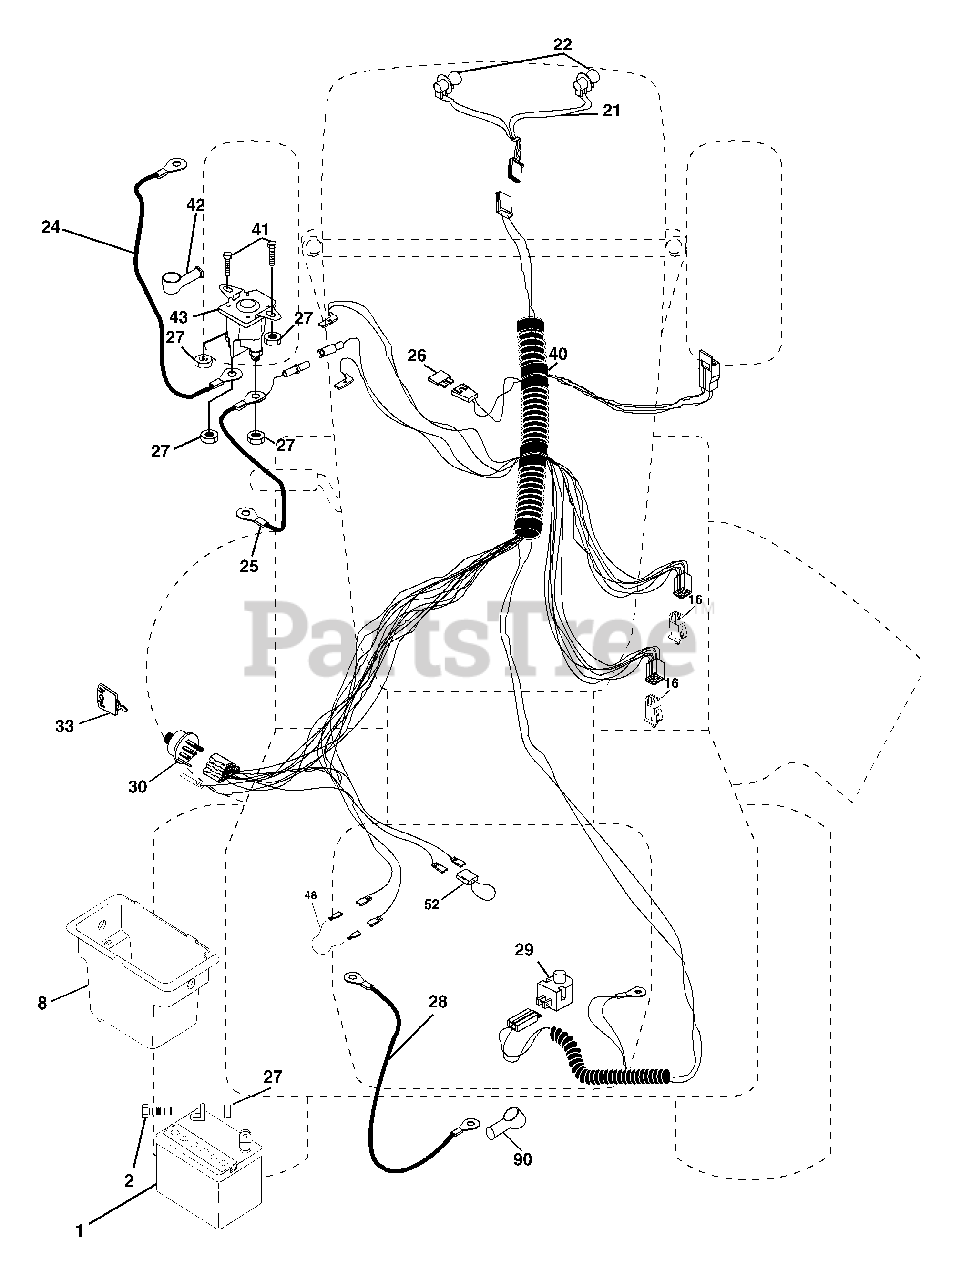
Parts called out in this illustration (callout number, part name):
1	Battery
2	Bolt, Hex Head 1/4-20 unc x 3/4
8	Box Battery Fender
16	Switch, Interlock
21	Harness, Light Socket
22	Bulb, Light
24	Cable, Battery, 6 Ga. Red, 11"
25	Cable, Battery, 6 Ga. Red, W/16 Wire
26	Fuse
27	Nut Keps Hex 1/4-20 unc
28	Cable, Ground, 6 Ga. Black, 12"
29	Switch, Plunger
30	Switch, Ignition
33	Key, Ignition
40	Harness, Ignition
41	Bolt, Hex Head, Fin. 1/4-20 x 1/2
42	Cover, Terminal, Red
43	Solenoid
48	Adaptor Ammeter Rectangular
52	Protection Wire Loop
90	Cover Terminal Battery
